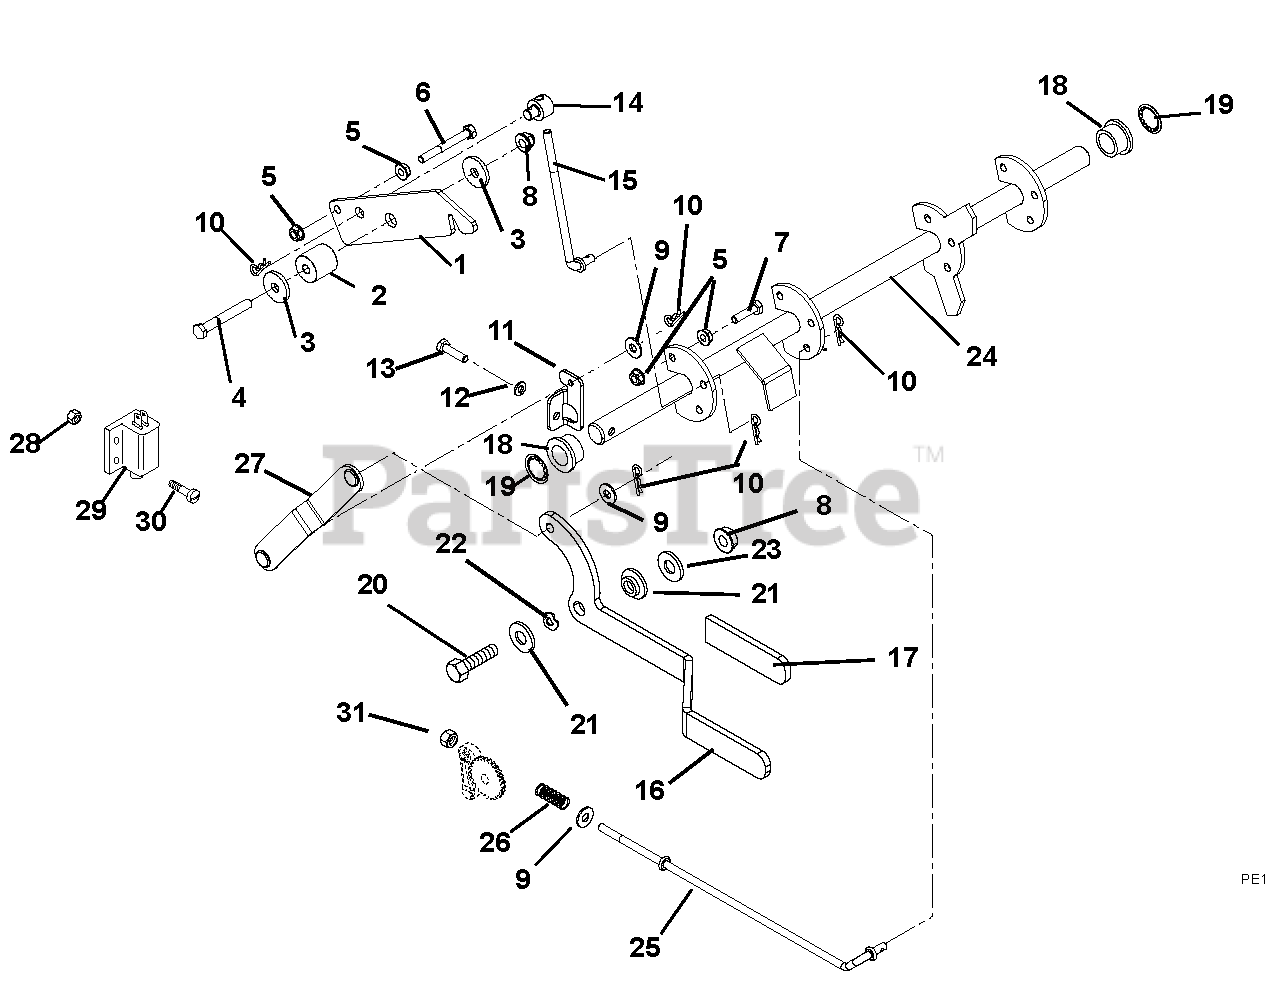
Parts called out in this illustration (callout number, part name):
1	Latch, Neutral
3	Washer, Flat Steel .344 x 1.125 x .135
4	Bolt, Hex .31-18 x 2.25 Grade 5
5	Nut, Locking Flange .250-20
6	Bolt, Hex .25-20 x 2.25 Grade 5
7	Bolt, Hex .25-20 x 1.00 Grade 5
8	Nut, Flange Nyloc 5/16-18
9	Washer, Flat Steel .312 x .734 x .065
10	Pin, Hair Internal .08 x .18 x 1.18
11	Crank, Parking Brake
12	Washer, Locking .25 x .062 Regular
13	Bolt, Hex .25-20 x 1.00 Grade 5
14	Trunnion, Brake
15	Brake, Link
16	Handle, Parking Brake
17	Grip, Parking Brake
18	Bushing, Flanged .750 x 1.000 x .625 x 1.250
19	Push Nut, .745 Shaft
20	Bolt, Hex .31-18 x 1.75 Grade 5
21	Bushing, Flange .325 x .501 x .250 x 1.12
22	Washer, Wave .50 x .75 x .015
23	Washer, Flat Steel, .328 x .87 x .179
24	Weldment, Brake Shaft
25	Rod, Brake
26	Spring, Compression .045 x .50 x 1.187
27	Link, Parking Brake
28	Nut, Locking Nylon 10-24 with Insert
29	Switch, Double Pole
30	Screw, Machine 10-24 x .75
31	Nut, Locking-Nylon .250-20
32	Kit, Brake
